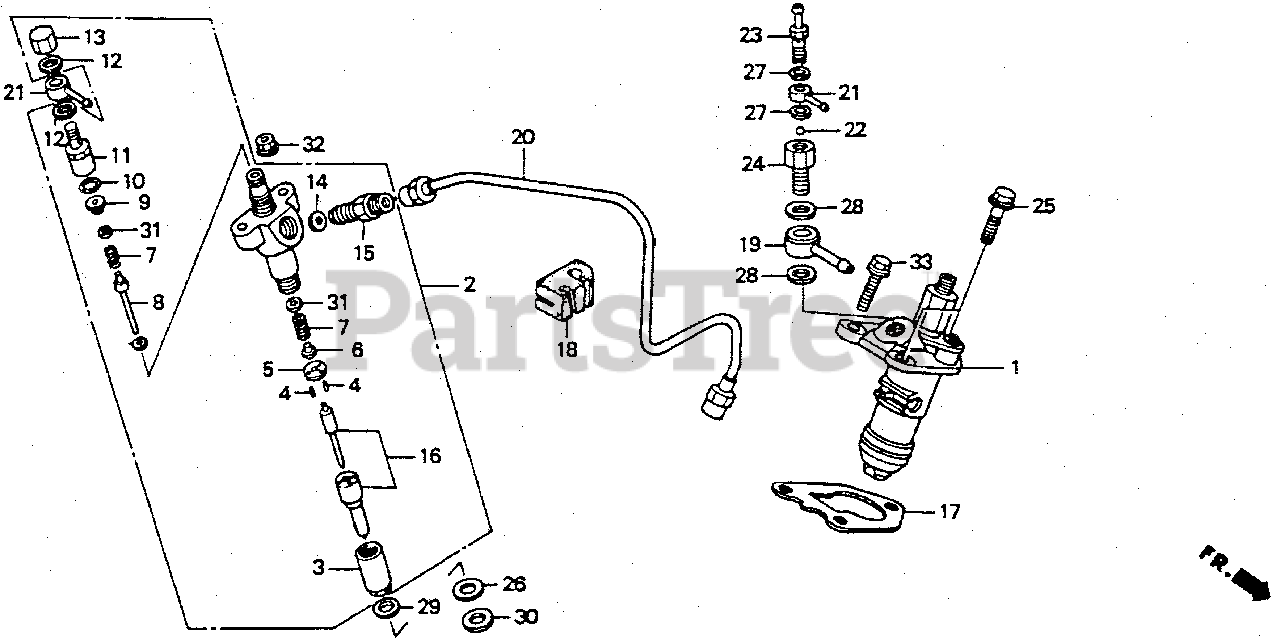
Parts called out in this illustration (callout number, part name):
1	PUMP ASSY., FUEL INJECTION
2	NOZZLE & HOLDER ASSY.
3	NUT, RETAINING
4	PIN (1.78X9.3)
5	SPACER
6	SEAT, SPRING (A)
7	SPRING, NOZZLE
8	ROD, PUSH
9	SEAT, SPRING (B)
10	O-RING
11	NUT, CAP
12	GASKET A
13	NUT
14	GASKET B
15	CONNECTOR, IN.
16	NOZZLE
17	GASKET, FUEL INJECTION PUMP (0.2) (C)
17	GASKET, FUEL INJECTION PUMP (0.3) (D)
17	GASKET, FUEL INJECTION PUMP (0.4) (E)
17	GASKET, FUEL INJECTION PUMP (0.1) (A)
17	GASKET, FUEL INJECTION PUMP (0.15) (B)
17	GASKET, FUEL INJECTION PUMP (0.5) (F)
17	GASKET, FUEL INJECTION PUMP (0.6) (G)
18	RUBBER, FUEL TUBE CLAMP
19	JOINT, FUEL
20	PIPE A, FUEL
21	JOINT, AIR BREATHER (B)
22	BALL, CHECK
23	BOLT, AIR BREATHER (8X20)
24	BOLT, FUEL JOINT (12X25.5)
25	BOLT, ROTARY TRANSMISSION
26	WASHER, PLAIN (7MM)
27	WASHER (8MM)
28	WASHER, FUEL JOINT
29	GASKET A, NOZZLE (0.8)
29	GASKET B, NOZZLE (1.0)
29	GASKET, NOZZLE
29	GASKET D, NOZZLE (1.4)
30	GASKET, SPECIAL (7MM)
31	SHIM A (0.50)
31	SHIM B (0.51)
31	SHIM C (0.52)
31	SHIM D (0.53)
31	SHIM E (0.54)
31	SHIM F (0.55)
31	SHIM G (0.56)
31	SHIM H (0.57)
31	SHIM I (0.58)
31	SHIM J (0.59)
31	SHIM K (0.60)
31	SHIM L (0.70)
31	SHIM M (0.80)
31	SHIM N (0.90)
32	NUT, FLANGE (6MM)
33	BOLT, FLANGE (8X25)
